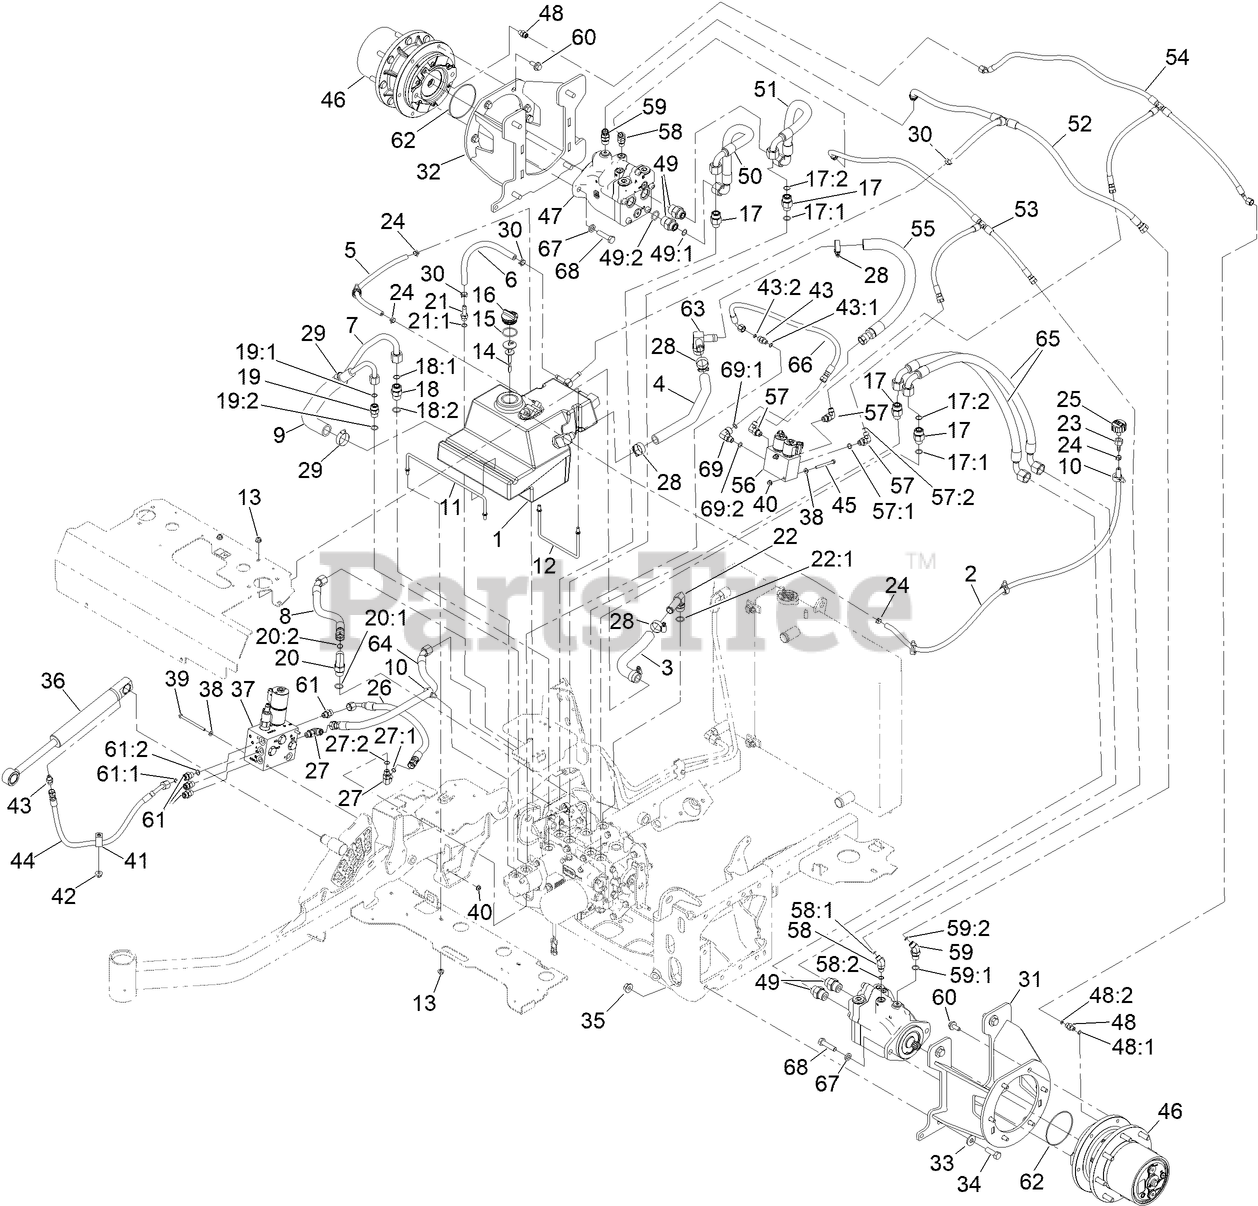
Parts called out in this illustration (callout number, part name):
1	HYD RESERVOIR ASM
3	HOSE-RETURN
4	HOSE-RETURN
7	TUBE ASM
8	HOSE ASM-HYD HP
9	HOSE-SUCTION
10	CLIP-TIE
11	ROD-SUPPORT, HYD TANK
12	ROD-SUPPORT, HYD TANK
13	NUT-HF, NI
14	DIPSTICK
15	O-RING
16	PLUG-PLASTIC
17	FITTING-STRAIGHT
17:1	O-RING
17:2	O-RING
18	FITTING-STRAIGHT
18:1	O-RING
18:2	O-RING
19	FITTING-STRAIGHT
19:1	O-RING
19:2	O-RING
20	FITTING-ELBOW, 90 DEG
20:1	O-RING
20:2	O-RING
21	ADAPTER-STRAIGHT
21:1	O-RING
22	FITTING-90
22:1	O-RING
23	FITTING-STRAIGHT
24	CLAMP-HOSE
25	BREATHER
26	HOSE ASM
27	FITTING-ELBOW, 90 DEG
27:1	O-RING
27:2	O-RING
28	CLAMP-HOSE
29	CLAMP-HOSE
30	CLAMP-HOSE
31	MOTOR MOUNT, L [BLACK]
32	MOTOR MOUNT, R [BLACK]
33	WASHER-SPRING
34	SCREW-HH
35	NUT-HHF
36	CYLINDER-LIFT
37	VALVE ASM-LIFT AND FOLD
38	WASHER-FLAT
39	SCREW-HH
40	NUT-HF
41	CLIP-LOOM
42	NUT-HF, NI
43	FITTING-HYD, STRAIGHT
43:1	O-RING
43:2	O-RING
44	HOSE ASM
45	SCREW-HH
46	PLANETARY ASM-11.96:1
47	MOTOR-HYD, PISTON, 30CC
48	FITTING-STRAIGHT
48:1	O-RING
48:2	O-RING
49	FITTING-STRAIGHT
49:1	O-RING
49:2	O-RING
50	HOSE-HP
51	HOSE-HP
52	HOSE ASM-HYDLPTEE
53	HOSE ASM-HYD HP TEE
54	HOSE ASM-HYD HP TEE
55	HOSE ASM-HYDLP
56	VALVE-HYD, BRK-2SPD
57	FITTING-ELBOW, 90 DEG
57:1	O-RING
57:2	O-RING
58	FITTING
58:1	O-RING
58:2	O-RING
59	FITTING-HYD, 45 DEG
59:1	O-RING
59:2	O-RING
60	SCREW-HHF
61	FITTING-STRAIGHT
61:1	O-RING
61:2	O-RING
62	O-RING
64	HOSE ASM-HYD HP
65	HOSE-HP
66	HOSE ASM-HYD HP
68	SCREW-HH
69	FITTING-HYD, 90 DEG
69:1	O-RING
69:2	O-RING
